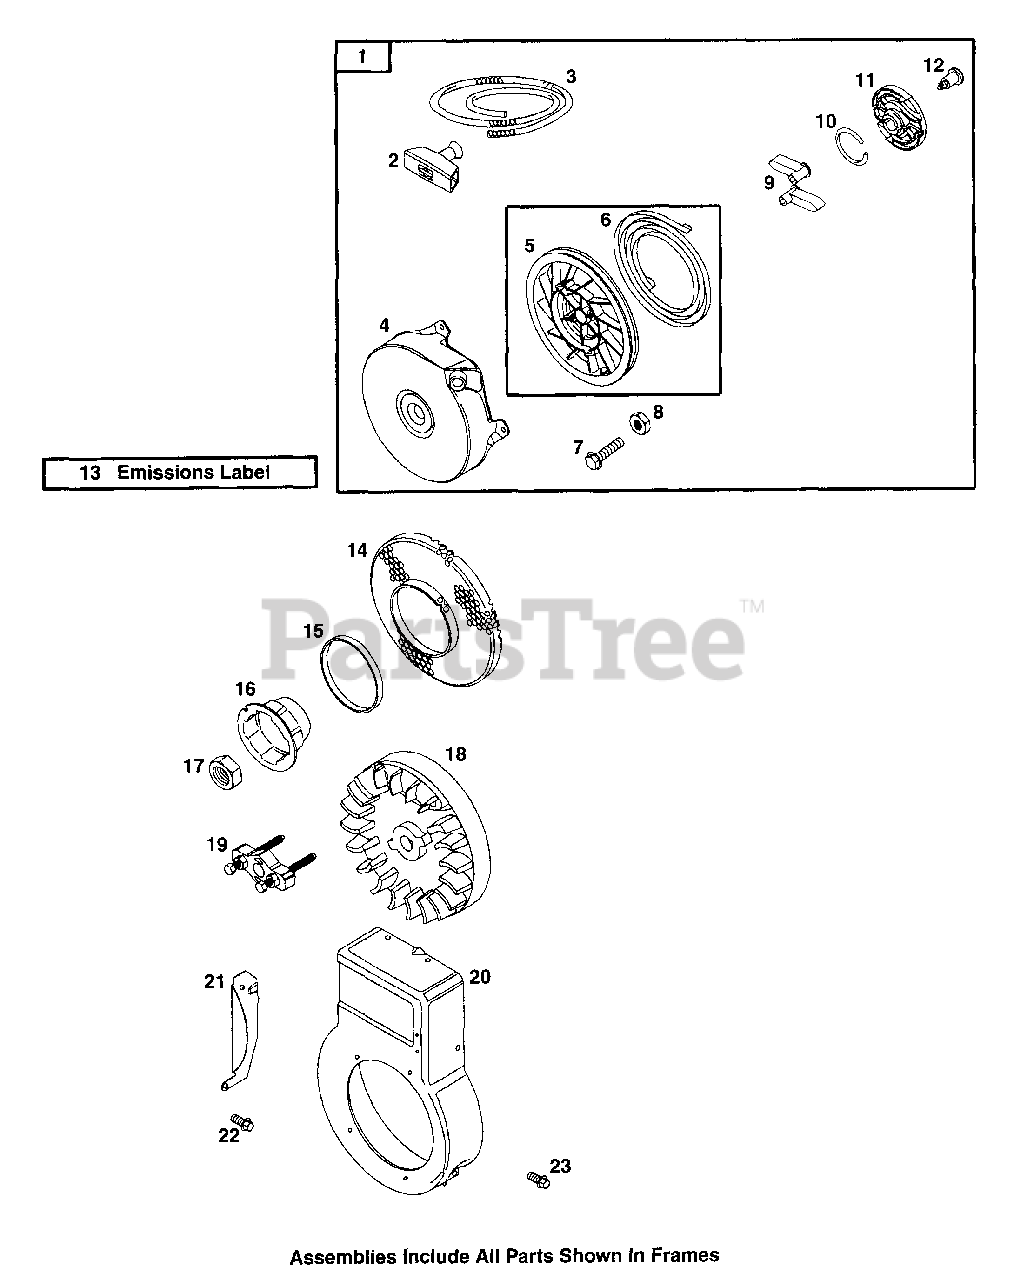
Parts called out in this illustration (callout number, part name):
1	Starter-Rewind
2	Starter Rope Grip
3	Starter Rope
4	Rewind Starter Housing
5	Pulley/Spring Assembly
6	Pulley/Spring Assembly
7	Screw (Rewind Starter)
8	Nut (Rewind Starter)
9	Ratchet Pawl
10	Friction Spring
11	Pawl Friction Plate
12	Screw (Pawl Friction Plate)
13	Emissions Label
14	Rotating Screen
15	Rotating Trim Ring
16	Flywheel Cup
17	Nut (Flywheel)
19	Flywheel Puller
20	Housing-Blower
21	Flywheel Guard
22	Screw (Flywheel Guard)
23	Screw (Blower Housing)
